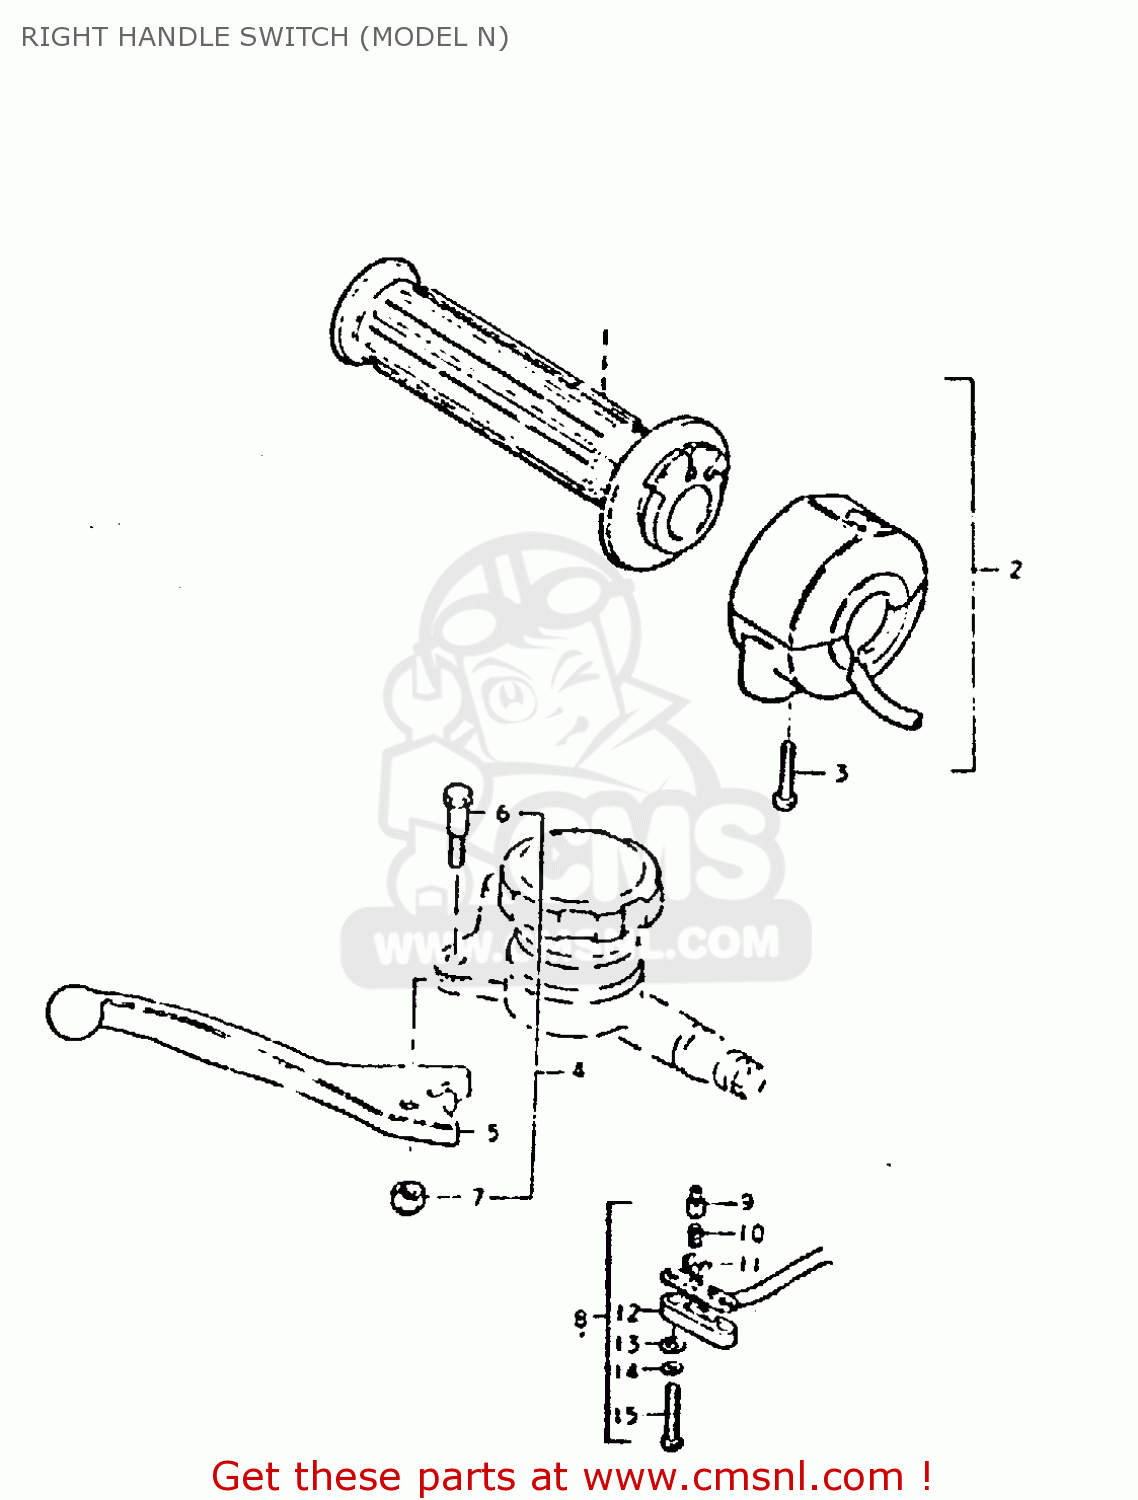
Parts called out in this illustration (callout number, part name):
1	GRIP, THROTTLE
2	CASE ASSY, THROTTLE
3	SCREW
4	LEVER ASSEMBLY,BRAKE
5	LEVER,BRAKE
6	BOLT
7	NUT 6MM
8	SWITCH ASSY,STOP
9	HOLDER
10	SPRING
13	WASHER
14	LOCK WASHER
15	SCREW
